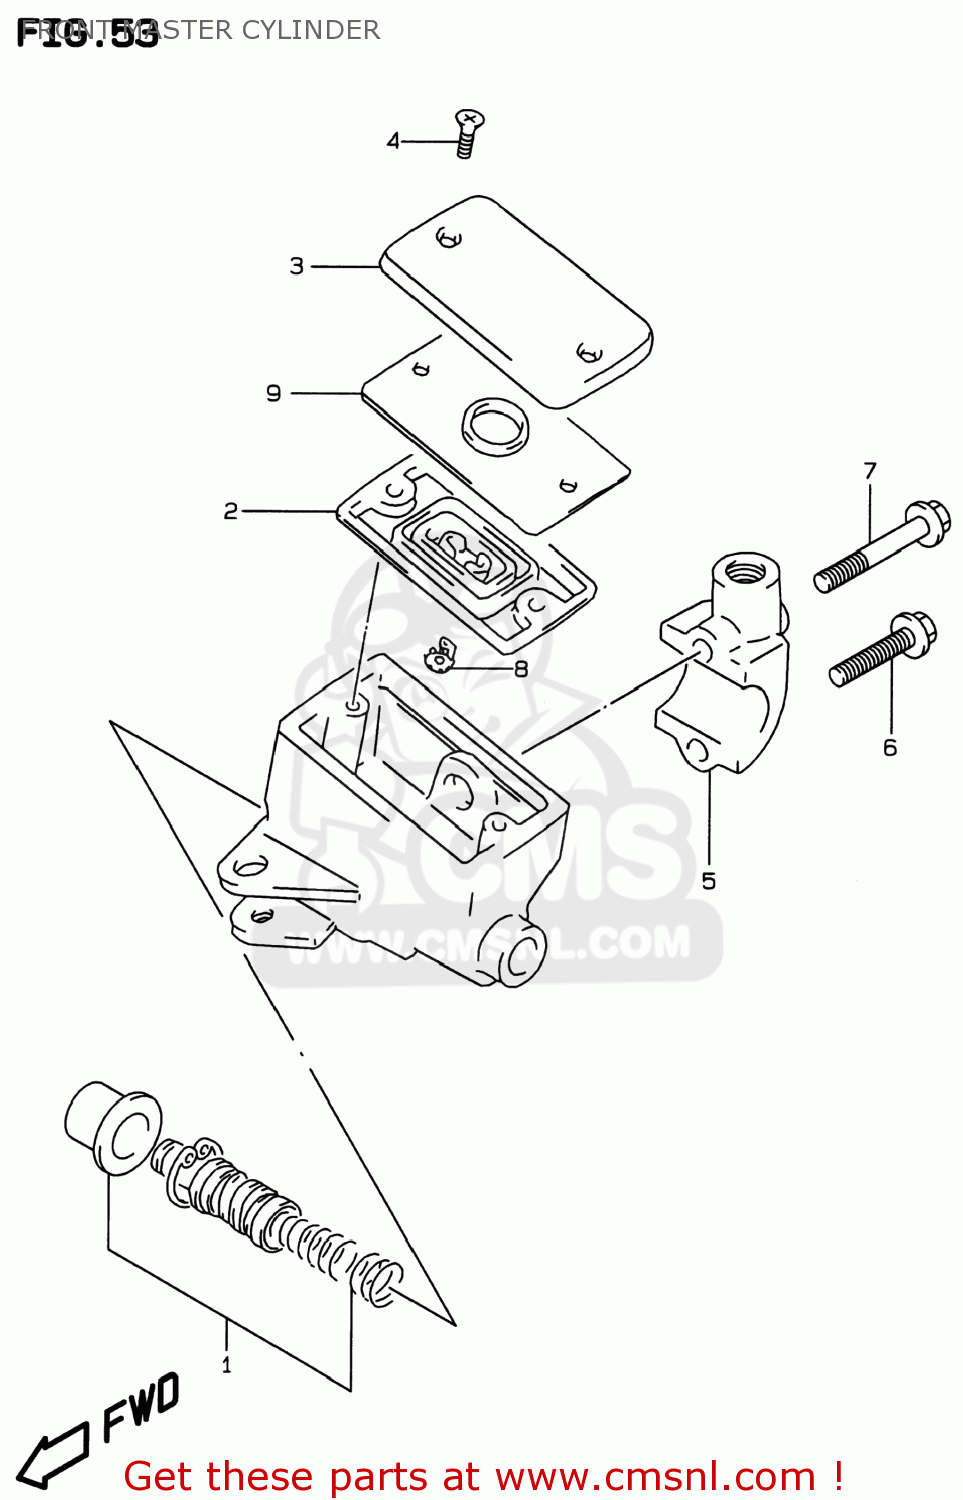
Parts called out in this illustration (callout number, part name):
1	PISTON & CUP SET
2	3
3	CAP
4	SCREW
5	HOLDER
6	BOLT(6X25)
7	BOLT(6X38)
8	PROTECTOR
9	PLATE,DIAPHRAGM
